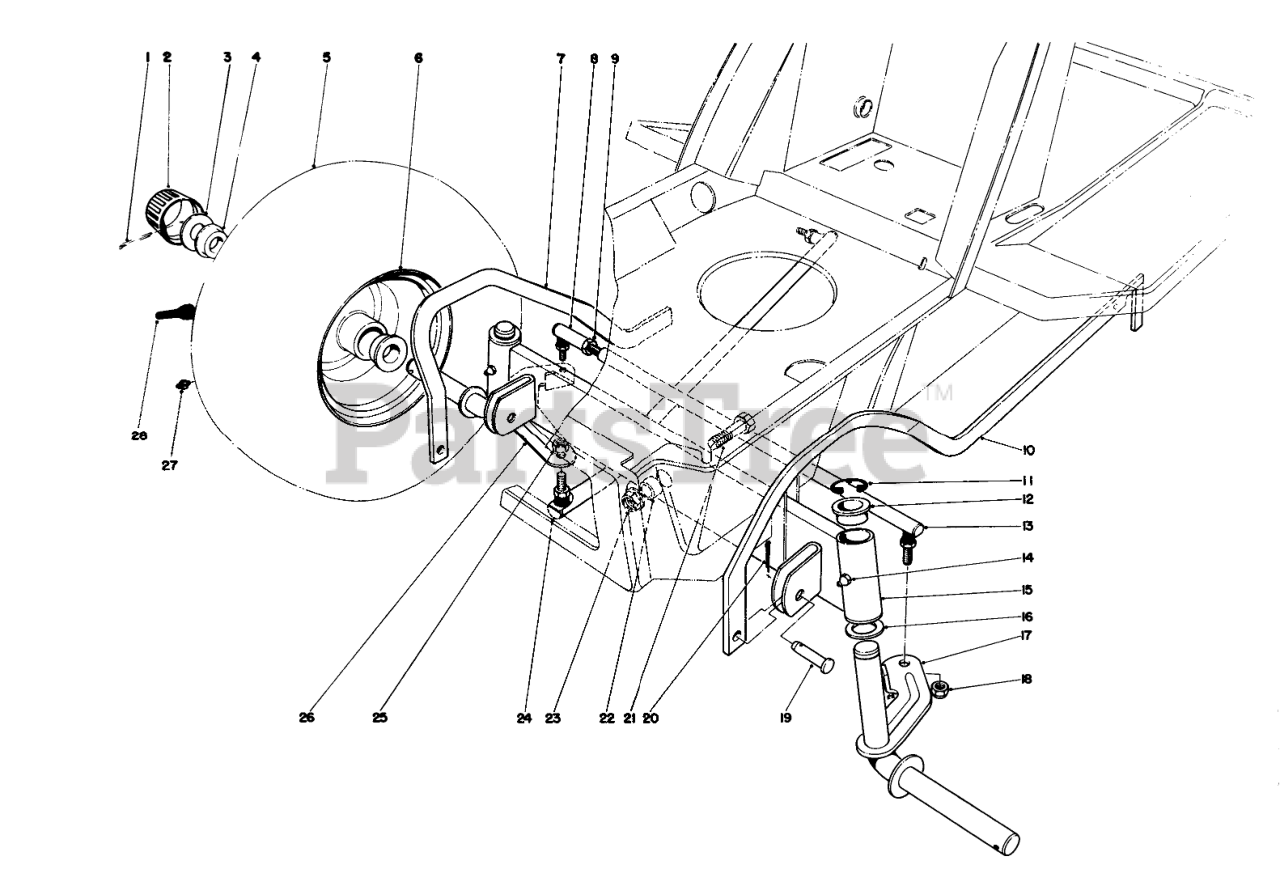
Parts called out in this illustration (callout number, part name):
1	PIN-COTTER
2	CAP-HUB
3	WASHER-PLAIN
4	Bearing
5	TIRE-FRONT
6	FRONT WHEEL
7	RH DECK PARALLEL LINK R
8	JOINT-BALL
9	NUT-JAM
10	LH DECK PARALEL LNKR
11	E-RING
12	BEARING-FLANGE
13	Tie Rod Steering (Incl. Ref. #8 & 9)
14	GREASE FITTING
15	Front Axle (Incl. Ref. #12)
16	WASHER-THRUST
17	Spindle L.H.
18	NUT-LOCK, NI
19	PIN-CLEVIS
20	PIN-COTTER
21	SCREW-HH
22	SPACER-AXLE, FRONT
23	NUT-HF
24	STEERING ARM B
25	NUT-HEX
26	SPINDLE WA RH B
27	FITTING-GREASE
28	STEM-VALVE
